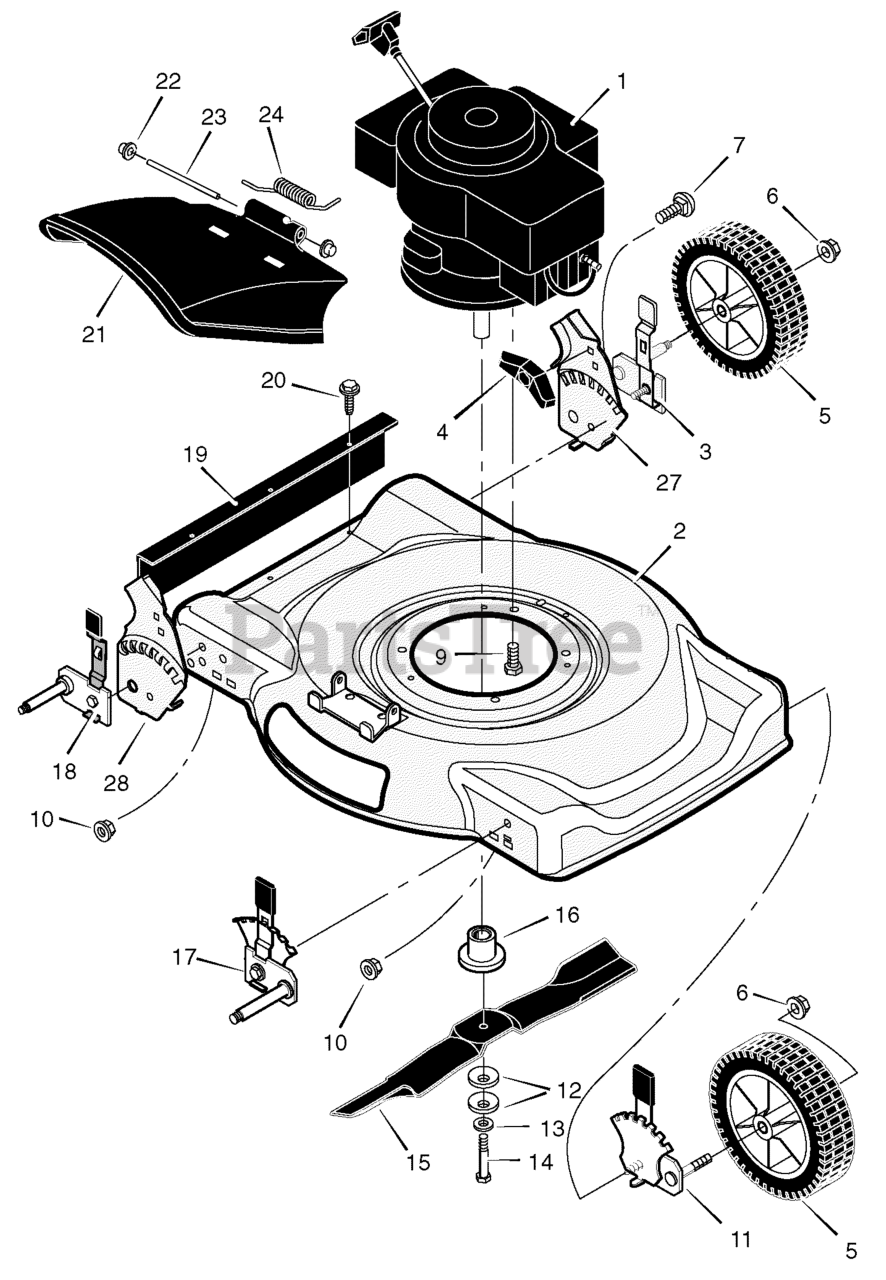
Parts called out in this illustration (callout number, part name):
1	Engine
2	Housing
3	Height Adjuster, Left Rear
5	Wheel and Tire
6	Locknut, Flange
7	Bolt, Carriage
9	Bolt, Engine
10	Nut
11	Height Adjuster, Left Front
12	Washer, Belleville
13	Washer
14	Bolt, Hex
16	Adapter, Blade
17	Height Adjuster, Right Front
18	Height Adjuster, Right Rear
19	Guard, Rear *
20	Screw *
21	Deflector, Chute *
22	Push-On Cap *
23	Pin, Pivot *
24	Spring
27	Bracket, Left Handle
28	Bracket, Right Handle
